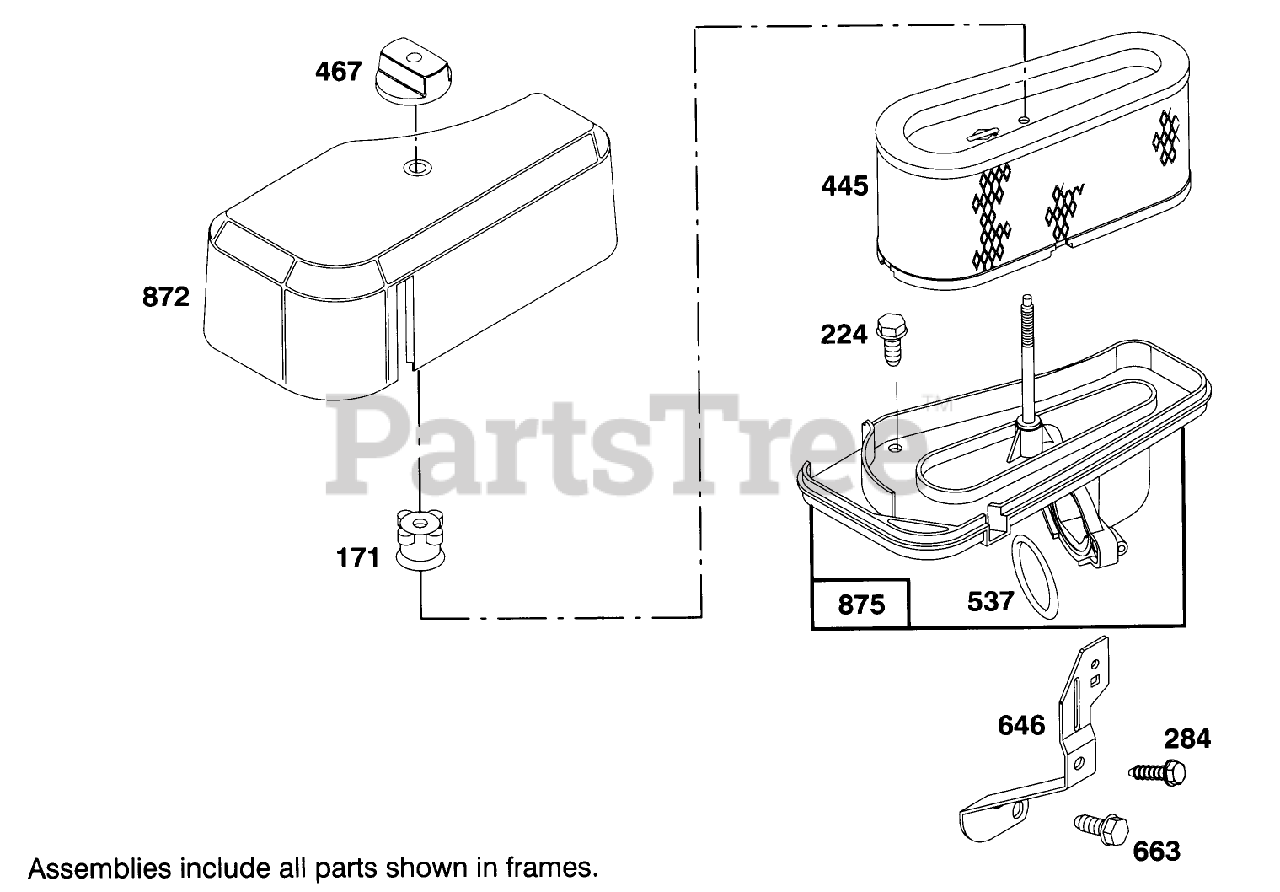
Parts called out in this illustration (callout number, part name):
224	Screw-Sem
284	Screw
445	Filter-Air
537	O-Ring
646	Brace-Air Cleaner
663	Screw
872	Cover-Air Cleaner
875	Base-Air Cleaner
